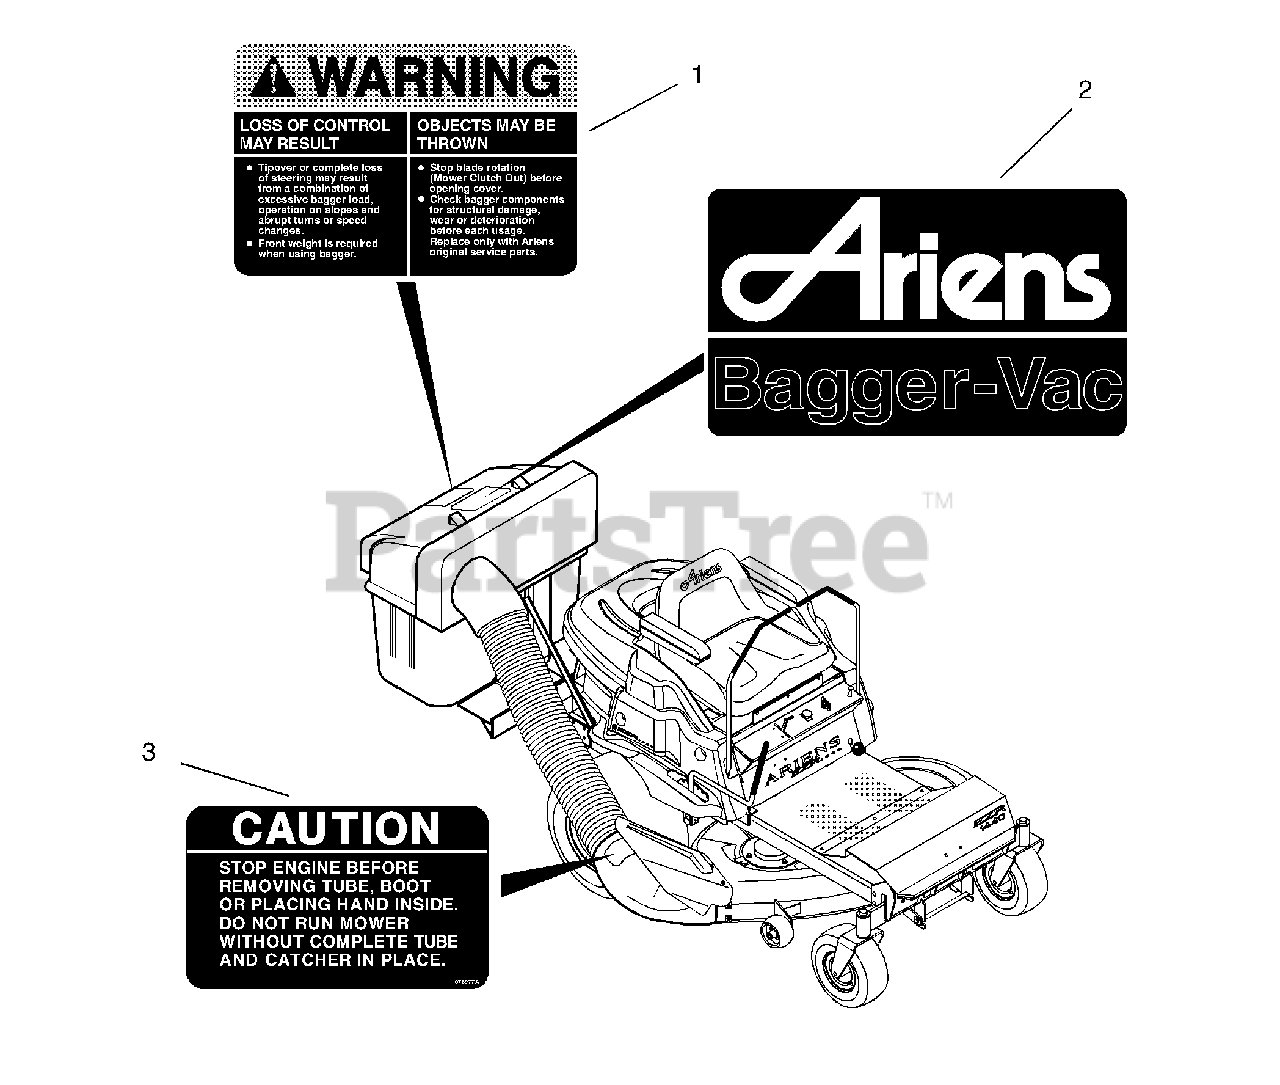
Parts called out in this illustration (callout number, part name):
1	DECAL, WARNING EZR BAGGER
2	DECAL-BAGGER VAC
3	DECAL-BOOT CAUTION
